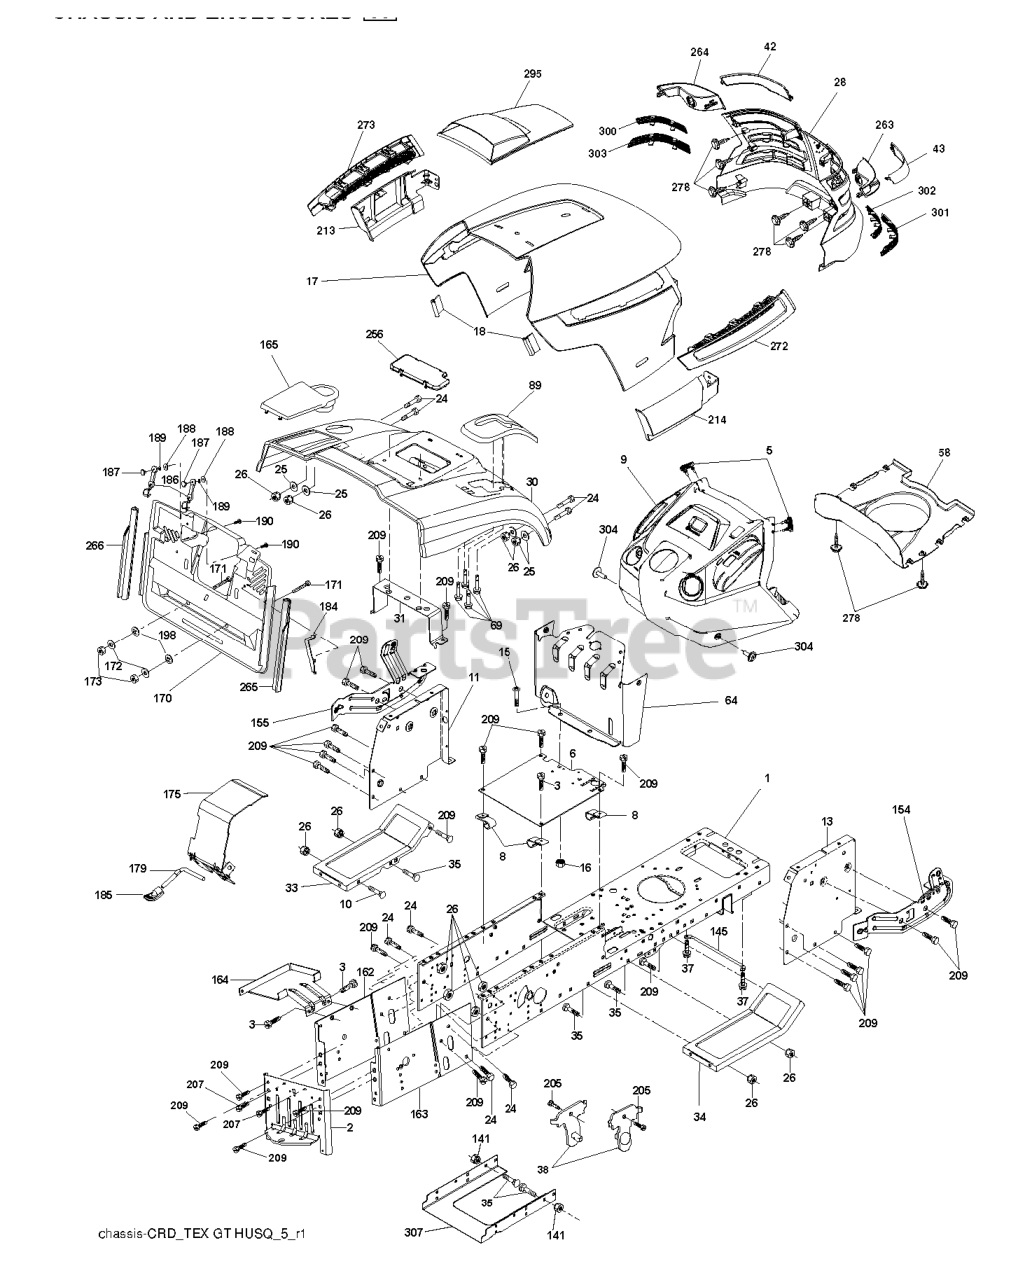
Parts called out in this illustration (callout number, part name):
2	DRAWBAR
3	SCREW 3/8-16X3/4
5	BUMPER DASH
6	PLATE
8	CLIP,INSULATOR
10	BOLT D
11	PANEL DASH LH
13	PANEL DASH RH
15	Screw, Machine, Truss Head 5/16-18 UNC x 3/4
16	NUT
17	HOOD
18	BUMPER.HOOD.TEX.HUSQVARNA
25	WASHER
26	NUT
28	GRILL.ASM.HUSQ.TG/CRD.W/TRIM
30	CONSOLE.CRD.AUTO.GRY
31	BRACKET SUPPORT FENDER
33	FOOTREST PNT LH
34	FOOTREST PNT RH
37	Screw 5/16-18 x 1/2 Hex, Self Tapping 5/16-18 x 1/2
38	BRACKET ASM PIVOT MOWER REAR
42	LENS.LH.TEX.GT.HUSQ.CL
43	LENS.RH.TEX.GT.HUSQ.CL
58	AIR.DUCT.HOOD.TEX.GT.HUSQ
69	SCREW.HI-LO.CONSOLE
89	CONSOLE.CRD.AUTO.GREY.2005
141	NUT LOCK FLG 3/8-16 UNC
145	ROD.PIVOT.HOOD
162	BRACKET
163	BRACKET EXTEN CHASSIS RH CRD
165	RP.COVER.BATTERY.CRD.GREY
172	WASHER
175	DOOR TRAP
179	ROD PIVOT FBI
184	BRACKET.ACTUATOR.BAGGER.SRD
186	LATCH ASSY
187	WELDNUT
189	LOCKWASHER #10
190	SCREW
207	SCREW, 5/16-18 X 1/2
209	SCREW, 3/8-16X3/4
213	SKIRT.HOOD.SIDE.HUSQ.LH.GREY
214	SKIRT.HOOD.SIDE.HUSQ.RH.GREY
256	COVER FENDER CRD
263	BEZEL.RH.TEX.GT.HUSQ
264	BEZEL.LH.TEX.GT.HUSQ
265	SEALING
266	SEALING
272	VENT.SIDE.HOOD.HUSQ.RH.GREY
273	VENT.SIDE.HOOD.HUSQ.LH.GRAY
278	SCREW.#10 X 0.750.BOS
295	VENT.ASM.TORPHD.HUSQGT.LOGO.CL
300	INSERT.HEX.GRILL.HUSQ.
301	INSERT.HEX.GRILL.HUSQ.GREY
302	INSERT.HEX.GRILL.HUSQ.
303	INSERT.HEX.GRILL.HUSQ.
304	SCREW 14-20 X 5/8
